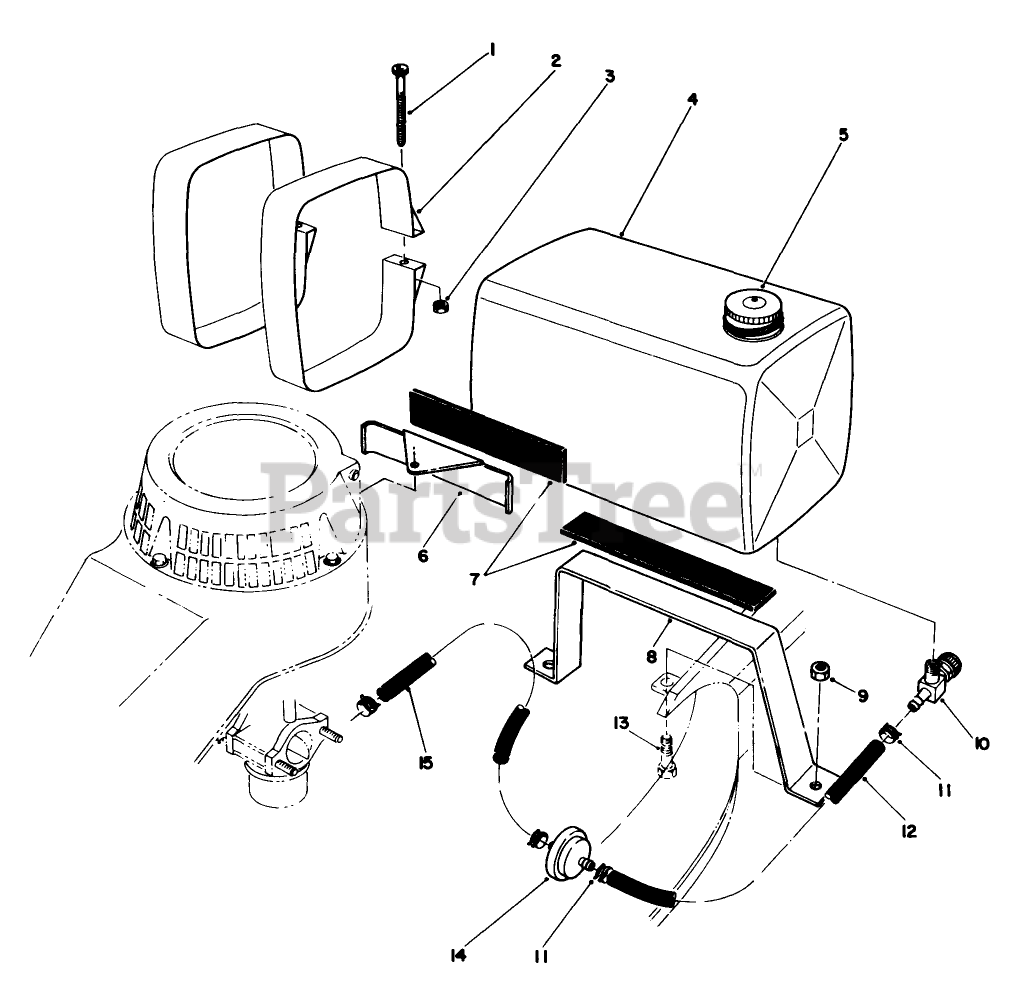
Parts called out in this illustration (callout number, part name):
1	SCREW-HSH
2	TANK STRAP WA
3	NUT-HEX
4	5 QT GAS TANK
6	FRT TANK MOUNT *
7	ISOLATOR PAD
8	TANK BOTTOM MOUNT *
9	NUT-LOCK, NI
11	CLAMP-FUEL LINE
12	HOSE-FUEL
13	SCREW-HH
14	FILTER-FUEL
15	HOSE-FUEL
